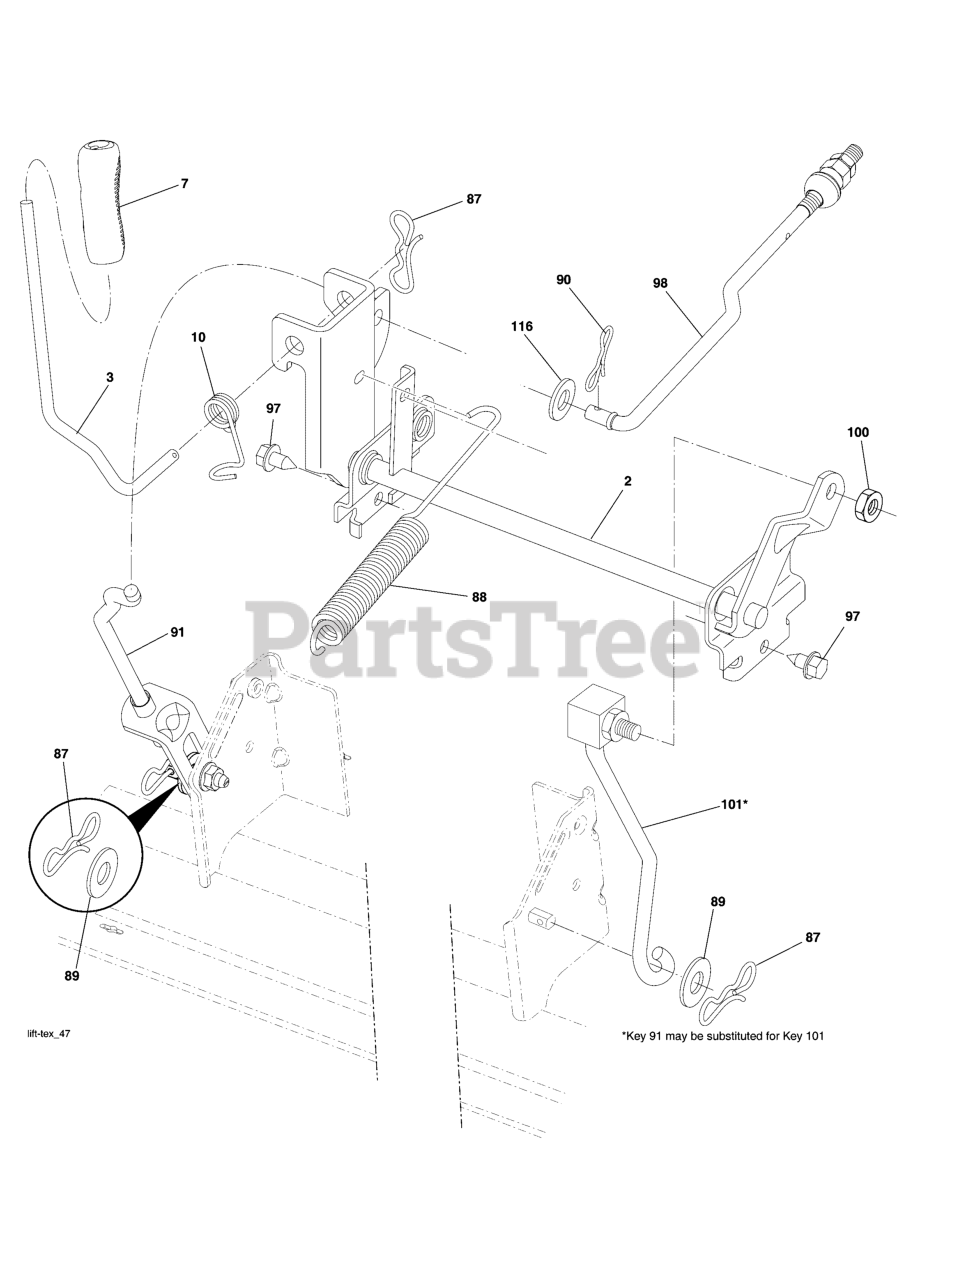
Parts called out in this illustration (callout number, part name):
2	Shaft Asm., Lift
3	Lever Asm., Lift RH
7	Grip, Lever
10	Spring Torsion
87	Pin Cotter 7/16 Bow Tie Lock
88	Spring Lift Assist
89	Washer Clear Zinc
90	Pin Cotter 5/16 Bow Tie Lock
91	Link Asm. Lift Rear
97	Screw 3/8-16 x .75 Smgml Tap/R.Z
98	Link Lift Susp. Front Mower
100	Nut Centerlock 3/8-16 unc
101	Link Asm. Lift Fixed
116	WASHER, 15/32 x 15/16 x 16 Ga.
